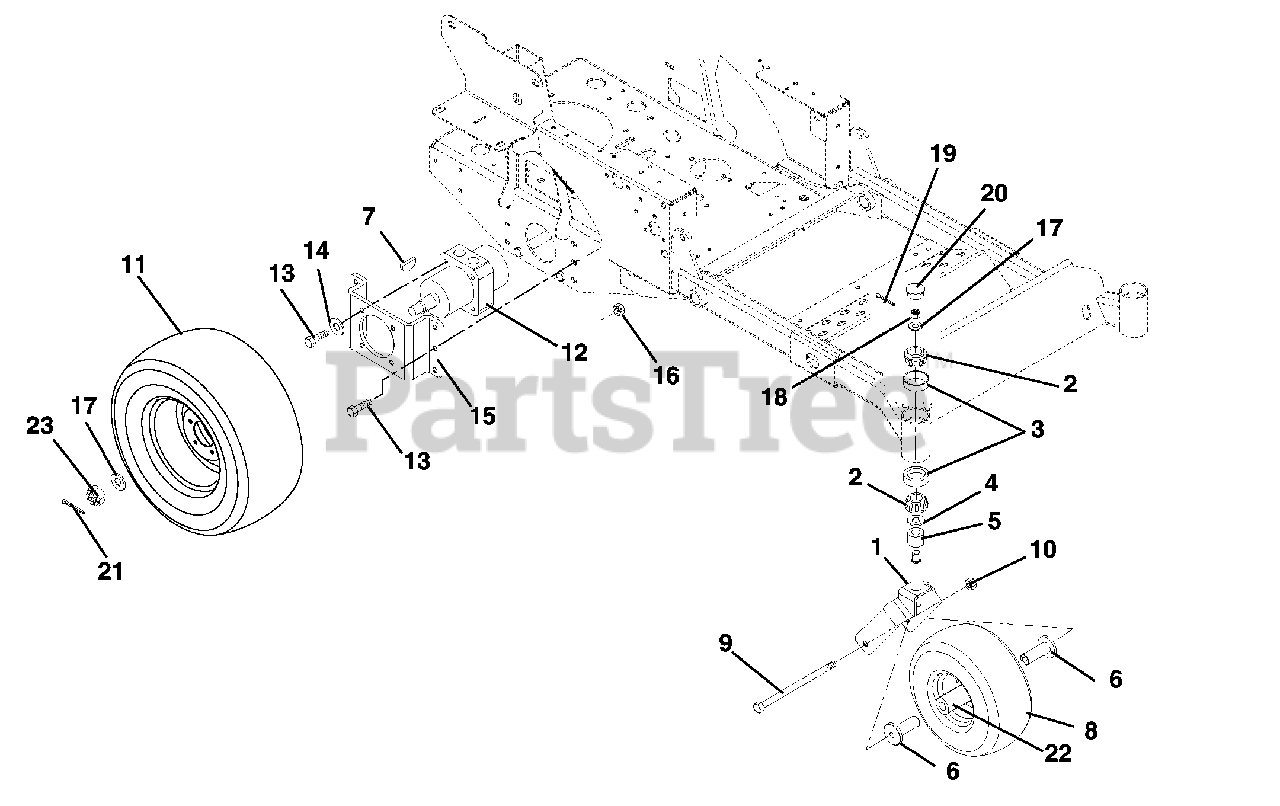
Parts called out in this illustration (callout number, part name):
1	Weldment, Front Fork
2	Bearing, Cone with Grease
3	Bearing, Cup 1.980 x .420
4	Bearing Seal 1.5 x 2 x .18
5	Spacer, PM, 1.03 I.D. x 1.5 O.D. x .375
6	Spacer, Wheel
7	Key, Woodruff .31 x 1.00
8	Wheel/Tire Assembly 5.25 x 13.00
9	Bolt, Hex .50-13 x 7.00 Grade 5
10	Nut, Locking Top Flange .50-13
11	Wheel, Tire Assembly 7.00 x 21.00
12	Motor, Hydraulic Wheel
13	Bolt, Hex .38-16 x 1.00 Grade 5
14	Washer, Locking .38 x .094 Regular
15	Bracket, Wheel Motor
16	Nut, Locking Top Flange .38-16
17	Washer, Flat Steel .755 x 1.375 x .062
18	Nut, Slotted .75-16
19	Pin, Cotter .16 x 1.00
20	Cap, Dust
21	Pin-Cotter .12 x 1.50 Extended Prong Square Cut
22	Bearing, 25MM I.D. x 52MM OD x 15MM
23	Nut, Lock Jam Patch
